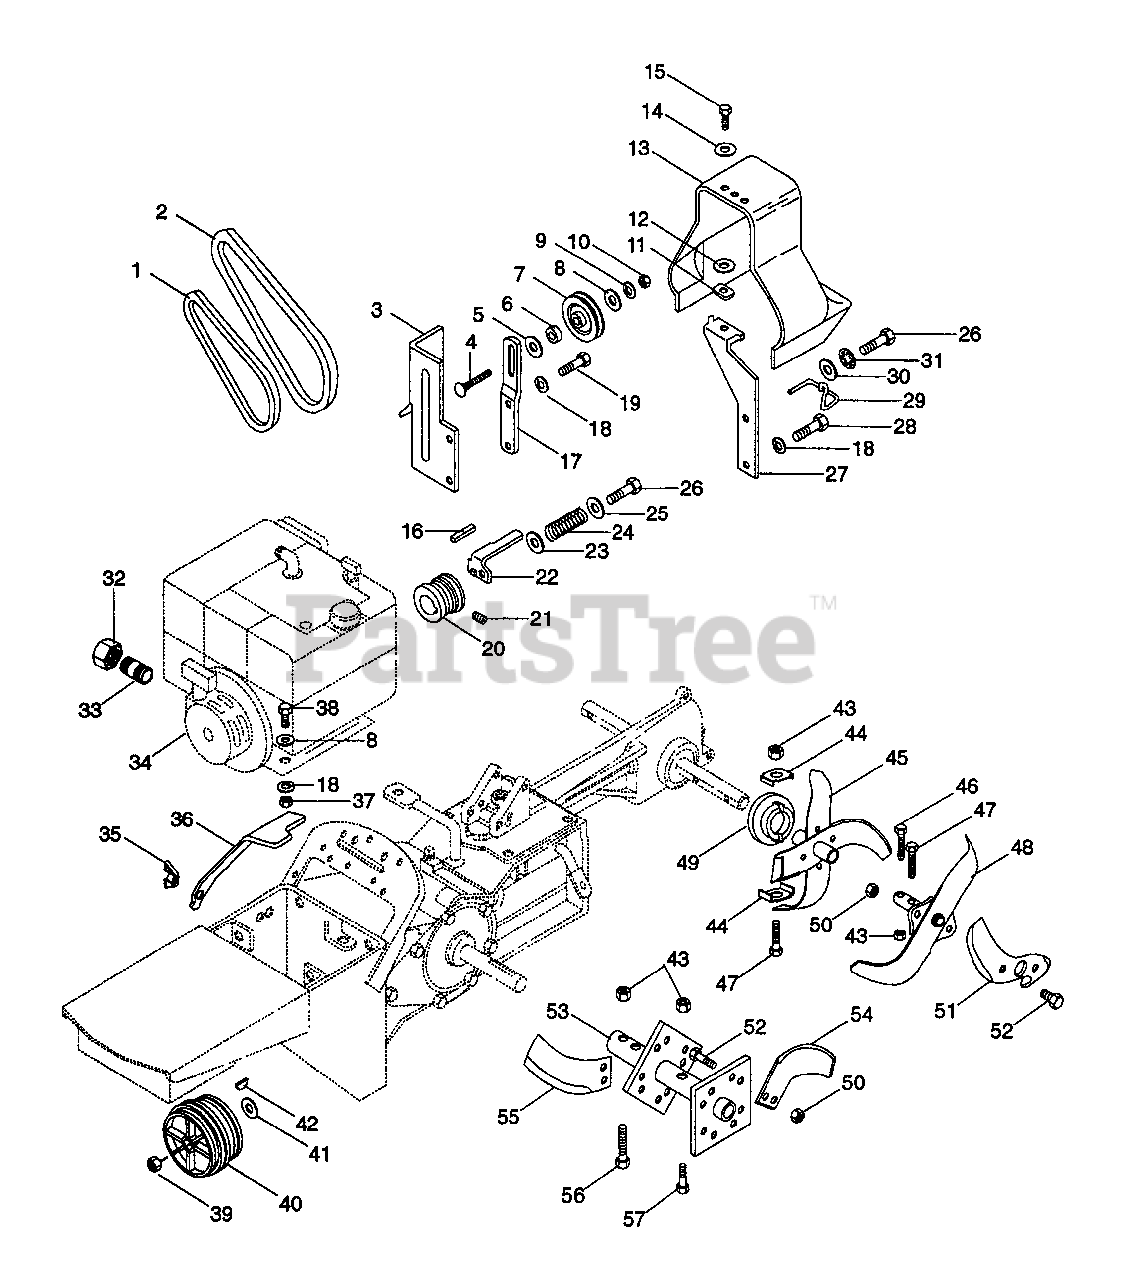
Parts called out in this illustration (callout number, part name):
1	V-BELT, 4L-WRAPPED
1	V-BELT, SAE 380-RAW EDGE (SET)
2	V-BELT, 3L-COGGED
3	HEAT SHIELD
4	BLT-RDHDSQNK .31-18X1.75 SHTPL
4	BLT-RDHDSQNK .31-18X1.38SHT PL
5	WSHR-FL-STL .380X.875X.179 PL
6	BEARING SPACER
6	SPCR, BRG .315X.50X.688X.281
7	IDLER
8	WSHR-FL-STL .38X.875X.083 PL
9	WSHR-LK .312X.097 PL HVY
10	NUT-HEX .312-18
11	NUT-SPEED U-TYPE .250-20
12	NUT-RETNR
13	BELT GUARD W/DECALS
14	WSHR-FL-STL .250X.562X.049 PL
15	BLT-HEX .25-20X.50 PL GR2
17	REVERSE IDLER BRACKET
18	KEY-SQ .188X1.0X.188 SAE 8630
18	KEY-SQ .25 X 1.25 X .25 SAE
18	WSHR-LK .312X.097 PL HVY
18	WSHR-LK .375X.115 HVY PL
19	BLT-HEX .31-24X.75 PL GR5
19	BLT-HEX .38-16X.75 PL GR2
20	ENGINE SHEAVE
21	SCR-SET .25-20X.25 SKHCUPNY OH
21	SCR-SET .32-18X.38 SKHCUPNL OH
22	BELT FINGER
23	WSHR-FL-STL .406X1.125X.125 PL
24	SG-COMP .125X.68X1.62
25	WSHR-FL-STL.406X.812X.065PL
26	BLT-HEX .31-24X1.00 PL GR5
26	BLT-HEX .38-16X2.00 PL GR2
27	BELT COVER BRACKET
28	BLT-HEX .31-24X.50 GR5
28	BLT-HEX .38-16X.63 PL GR2
29	FORWARD BELT FINGER
29	BELT FINGER
30	WSHR-FL-STL .323X.625X.062 PL
31	WSHR-LK-INT .313X.030 PL
32	HEX PIPE CAP 1/2 NPT
33	MALE PIPE NIPPLE 1/2 NPT
34	5 HP TEC 5020
34	7 HP TEC 7020
34	8 HP KOHLER #301515
34	6 HP TEC
34	8 HP KOHLER SPEC #301515
35	NUT-WING W/INSERT .312 - 18
36	BELT FINGER
37	NUT-HEX .312-18
37	NUT-HEX .375-16
38	BLT-HEX .31-18X1.00 PL GR 2
38	BLT-HEX .38-16X1.25 PL GR 2
39	NUT-LK-CTR .75-16 PL
40	DRIVE SHEAVE
41	WSHR-FL-STL .765X1.250X.062
42	KEY-FTHR .188X1.25X.187 SAE
43	NUT-LK-CTR .375-16 GR A PL
43	NUT-LK TOP .375-16 GR C YWZC
45	RH INNER TINE SPOOL
45	LH INNER TINE SPOOL
46	BLT-HEX .38-16X1.75 PL GR2
47	BLT-HEX .38-16X2.00 PL GR2
48	LH OUTER TINE SPOOL
48	RH OUTER TINE SPOOL
49	DUST CAP
50	NUT-LK-TOP .437-14 GR C PL
51	TURBO-TINE
52	BLT-HEX .44-14X1.00 GR5
53	INNER TINE HUB
54	L KNIFE TINE
55	R KNIFE TINE
56	BLT-HEX .38-16X2.75 GR8
57	BLT-HEX .38-16X2.00 GR8
